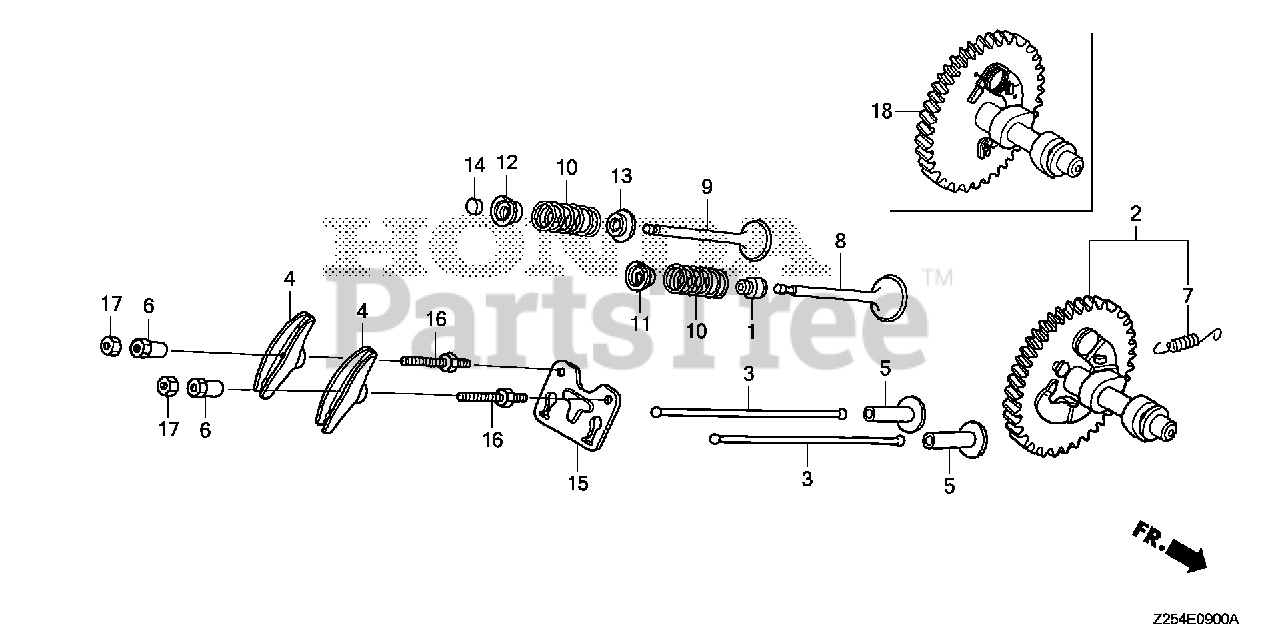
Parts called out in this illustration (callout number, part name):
1	SEAL, VALVE STEM
2	CAMSHAFT ASSY.
3	ROD, PUSH
4	ARM, VALVE ROCKER
5	LIFTER, VALVE
6	PIVOT, ROCKER ARM
7	SPRING, WEIGHT RETURN
8	VALVE, IN.
9	VALVE, EX.
10	SPRING, VALVE
11	RETAINER, IN. VALVE SPRING (EXHAUST SIDE)
12	RETAINER, EX. VALVE SPRING
13	SEAT, VALVE SPRING
14	ROTATOR, VALVE
15	PLATE, PUSH ROD GUIDE
16	BOLT, PIVOT (8MM)
17	NUT, PIVOT ADJ.
